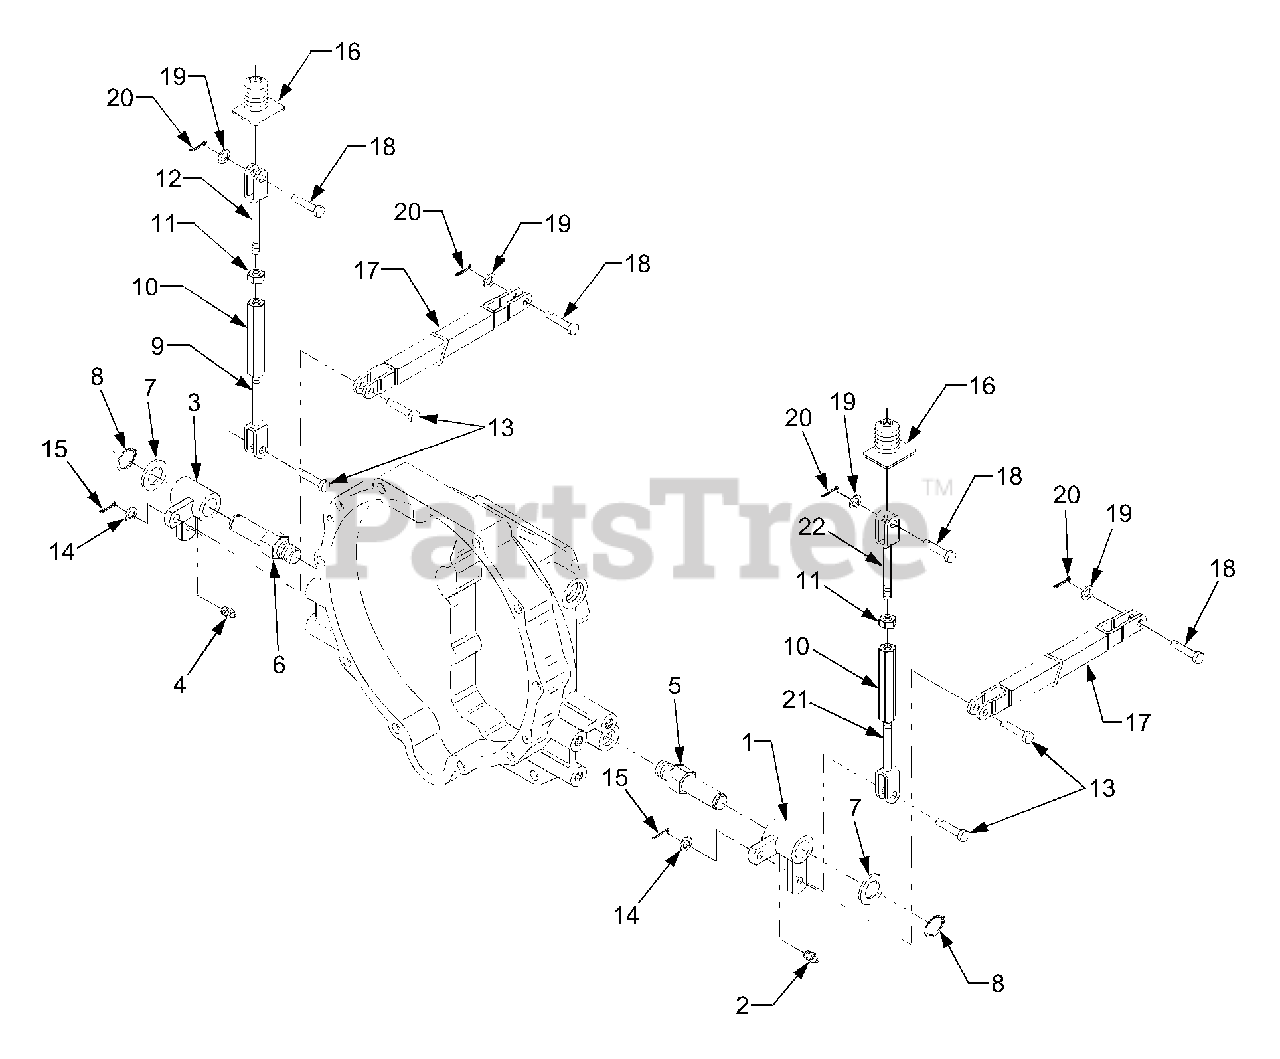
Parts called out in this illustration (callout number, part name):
2	Nipple, Grease
3	Lever, Brake (RH)
4	Nipple, Grease
5	Shaft, Brake (LH)
6	Shaft, Brake (RH)
7	Washer, Plain
14	Washer, Plain
17	Rod 3, Brake
19	Washer, Plain
21	Rod 1, Brake (LH)
22	Rod 2, Brake (LH)
